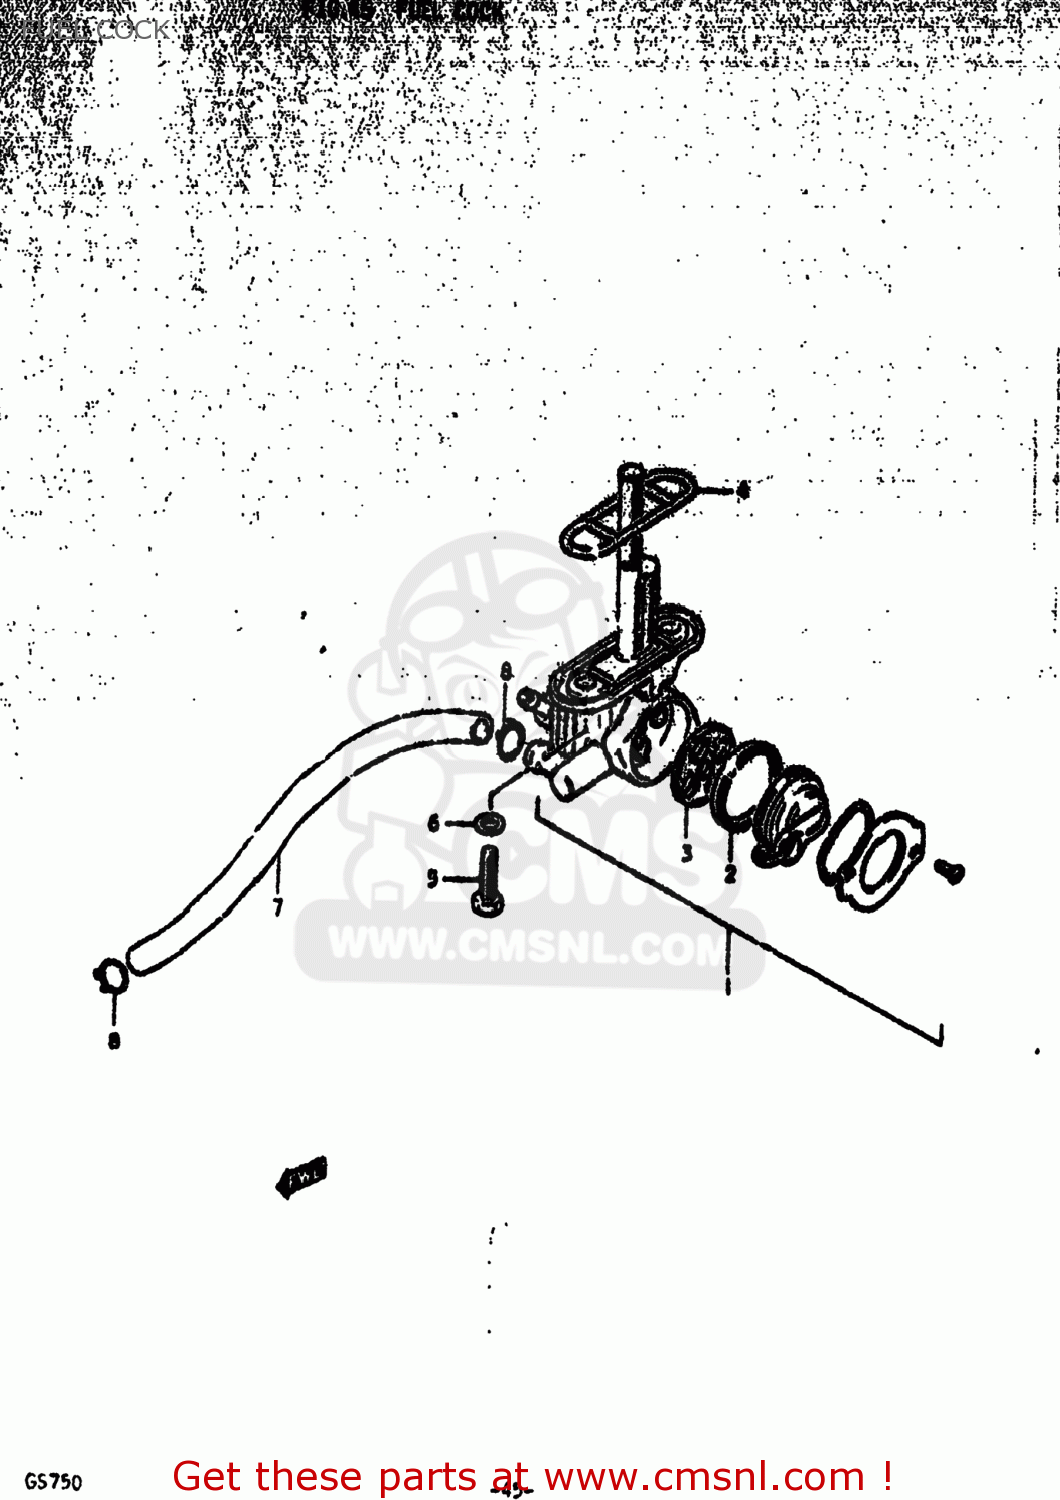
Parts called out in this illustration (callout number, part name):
1	COCK ASSEMBLY,FUEL
2	V SEAL,FUEL COCK
3	GASKET (NAS)
4	GASKET,FUEL COCK (NAS)
5	BOLT(6X20)
6	GASKET
7	HOSE
8	CLIP
